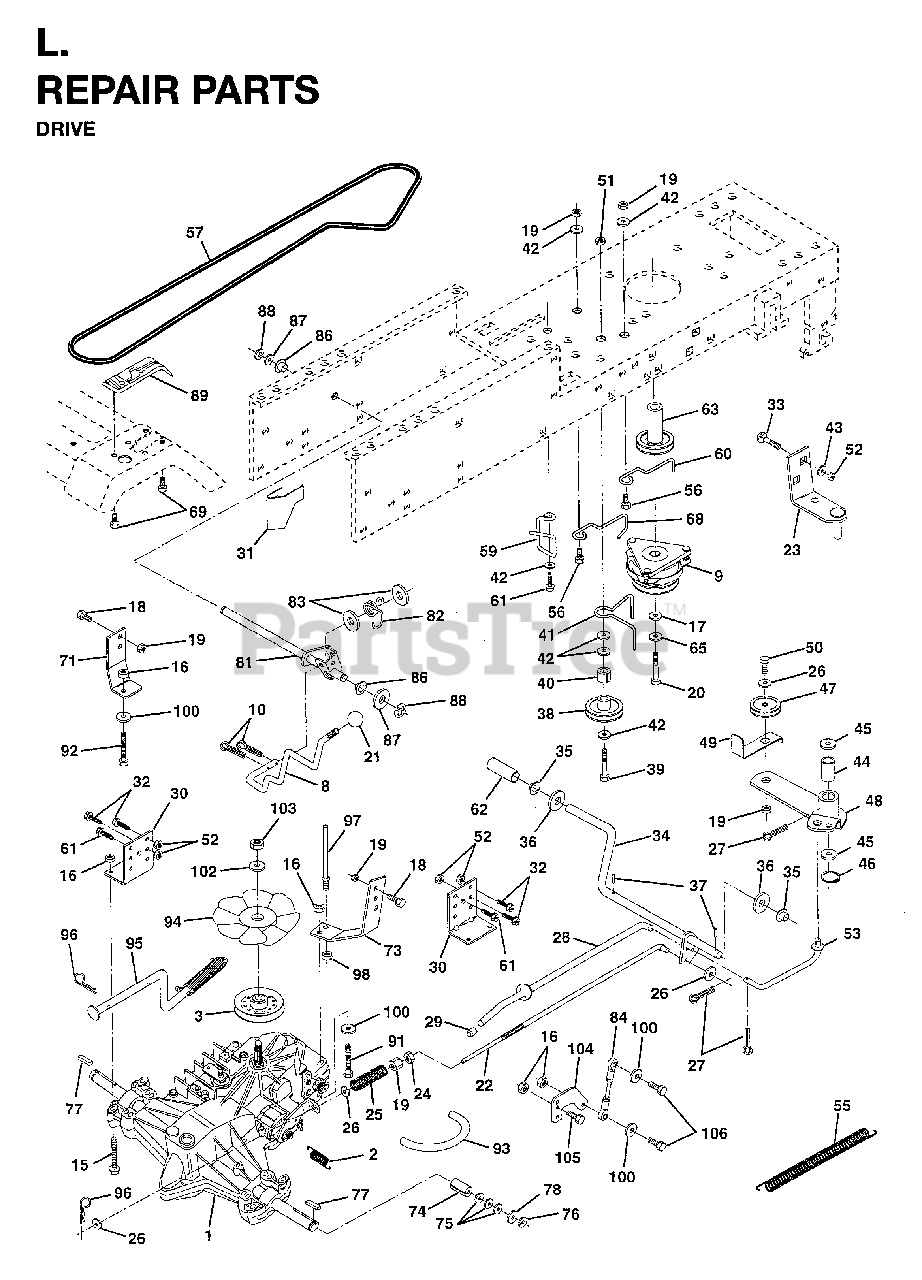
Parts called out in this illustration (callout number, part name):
1	TRANSAXLE ASSEMBLY
2	SPRING BRAKE
3	PULLEY, TRANSAXLE
8	SHIFT ROD
9	CLUTCH ELECT 1051B
10	PIN COTTER
15	BOLT HEX**
16	NUT.71038.31-18.HEX.NYLOCK
19	LOCKNUT
20	BOLT HEX
21	KNOB.DELUXE.(PISTOL.GRIP).BLAC
22	ROD BRAKE HYDRO
23	BRACKET ASM MTG
24	NUT.HEX.3/8-16UNC
25	SPRING ROD LT
26	WASHER
27	COTTER PIN
28	ROD BRAKE PARK LT
29	PLUNGER CAP
30	BRACKET TRANSAXLE
31	KEEPER BELT LH
32	BOLT
33	BOLT
34	SHAFT PEDAL FOOT
35	BEARING.NYLON
37	DRIVE PIN
38	PULLEY.IDLER.FLAT
40	SPACER T
41	BELT KEEPER LT
42	WASHER
43	WASHER
44	BEARING LT
45	WASHER LT
46	KLIP RING
47	IDLER PULLEY
48	ARM IDLER
49	RETAIN BELT
50	BOLT
51	LOCKNUT
52	LOCKNUT
53	LINK, CLUTCH LT
55	SPRING, RETURN LT
56	BOLT
57	DRIVE BELT, LTH & YTH TRACTORS
59	KEEPER CENTER SPAN
60	KEEPER BELT ENGLH
62	PEDAL COVER T
63	PULLEY CLU ELEC
65	LOCKWASHER
68	KEEPER,BLT ENG LT
69	SCREW.HI-LO.CONSOLE
71	STRAP RH TORQUE
73	STRAP LH TORQUE
74	SPACER SPLIT
76	E-RING LT
77	SQUARE KEY
81	SHAFT ASSY
82	SPRING,TORSION
86	BUSHING.STEERING.ROD
88	KLIP RING
89	CONSOLE HYDRO LT
92	HEX BOLT
93	FUEL LINE
94	FAN 7" HYDRO
95	CONTROL ARM, BYPASS HYDRO
96	RETAINER M
97	KEEPER BELT RH
98	NUT.HEX.3/8-16UNC
100	WASHER - 15X7.3X1.6
104	CONTROL ARM
106	BOLT.5/16-18X1-1/4 FULL.THREAD
